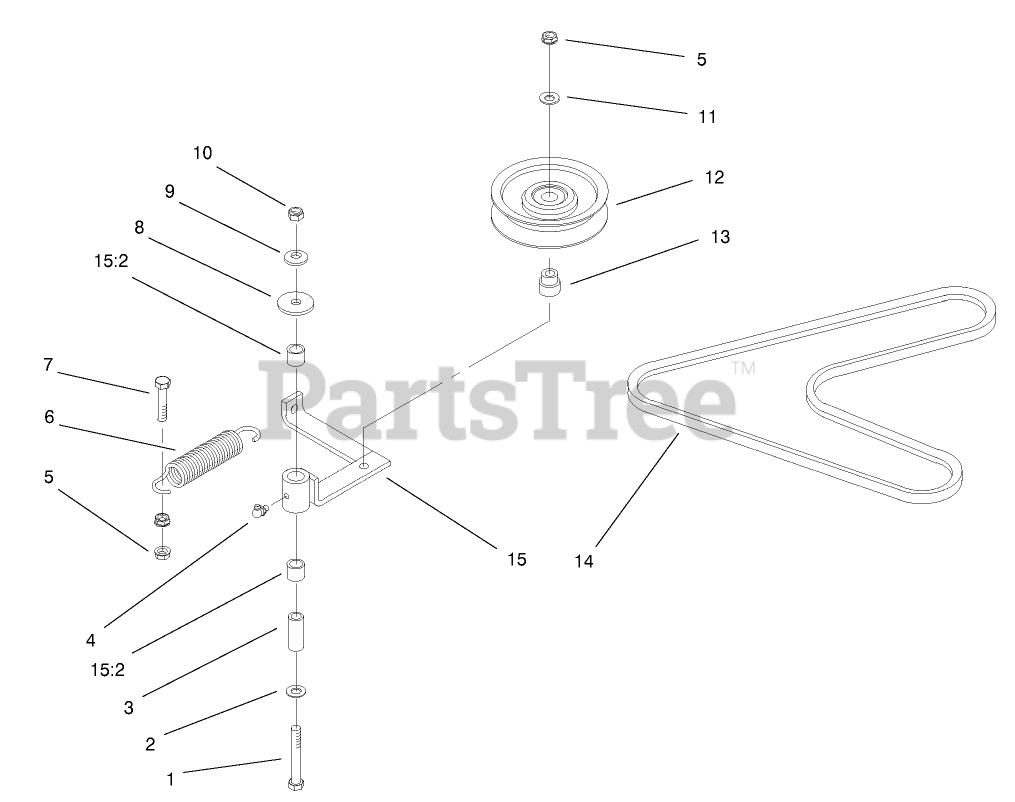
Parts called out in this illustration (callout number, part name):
1	SCREW-HH
2	WASHER-FLAT
3	Bushing
4	Zerk-Grease
5	NUT-HHF, WHIZ
6	Spring-Extension
7	SCREW-HH
8	Washer
9	Washer
10	NUT-LOCK, NI
11	WASHER-FLAT
12	Pulley-Idler
13	Bushing
14	Belt-Pump Drive
15	Idler Arm w/Bushings,Zerk
15:2	Bearing-Pivot
